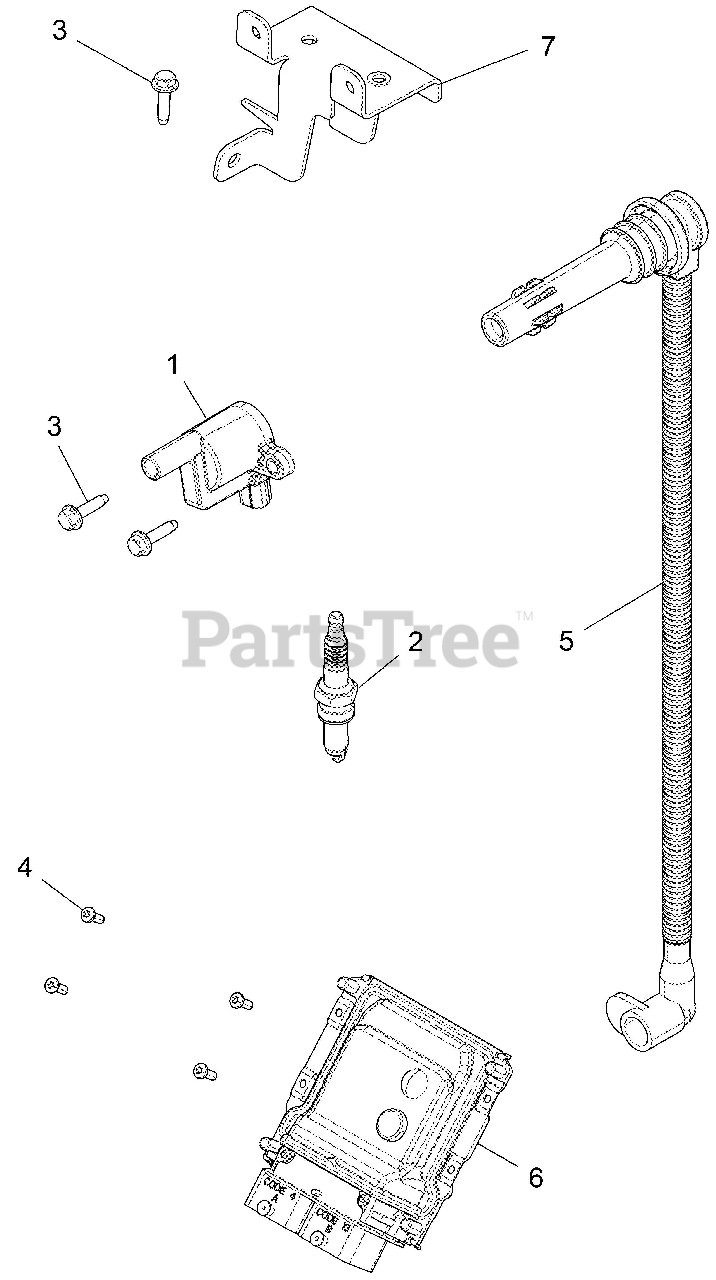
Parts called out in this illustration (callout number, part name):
1	COIL-IGNITION
2	SPARK PLUG-10 MM
3	SCR-M6X1.0X20,HXHD,FLG,TDFM,BL
4	SCR-#10X1/2-HI/LO-PN-T25,TRX-M
5	WIRE-SPARKPLUG,PTO
6	ECM-NO START,ME17
7	BRKT-AIRBOX MOUNT
